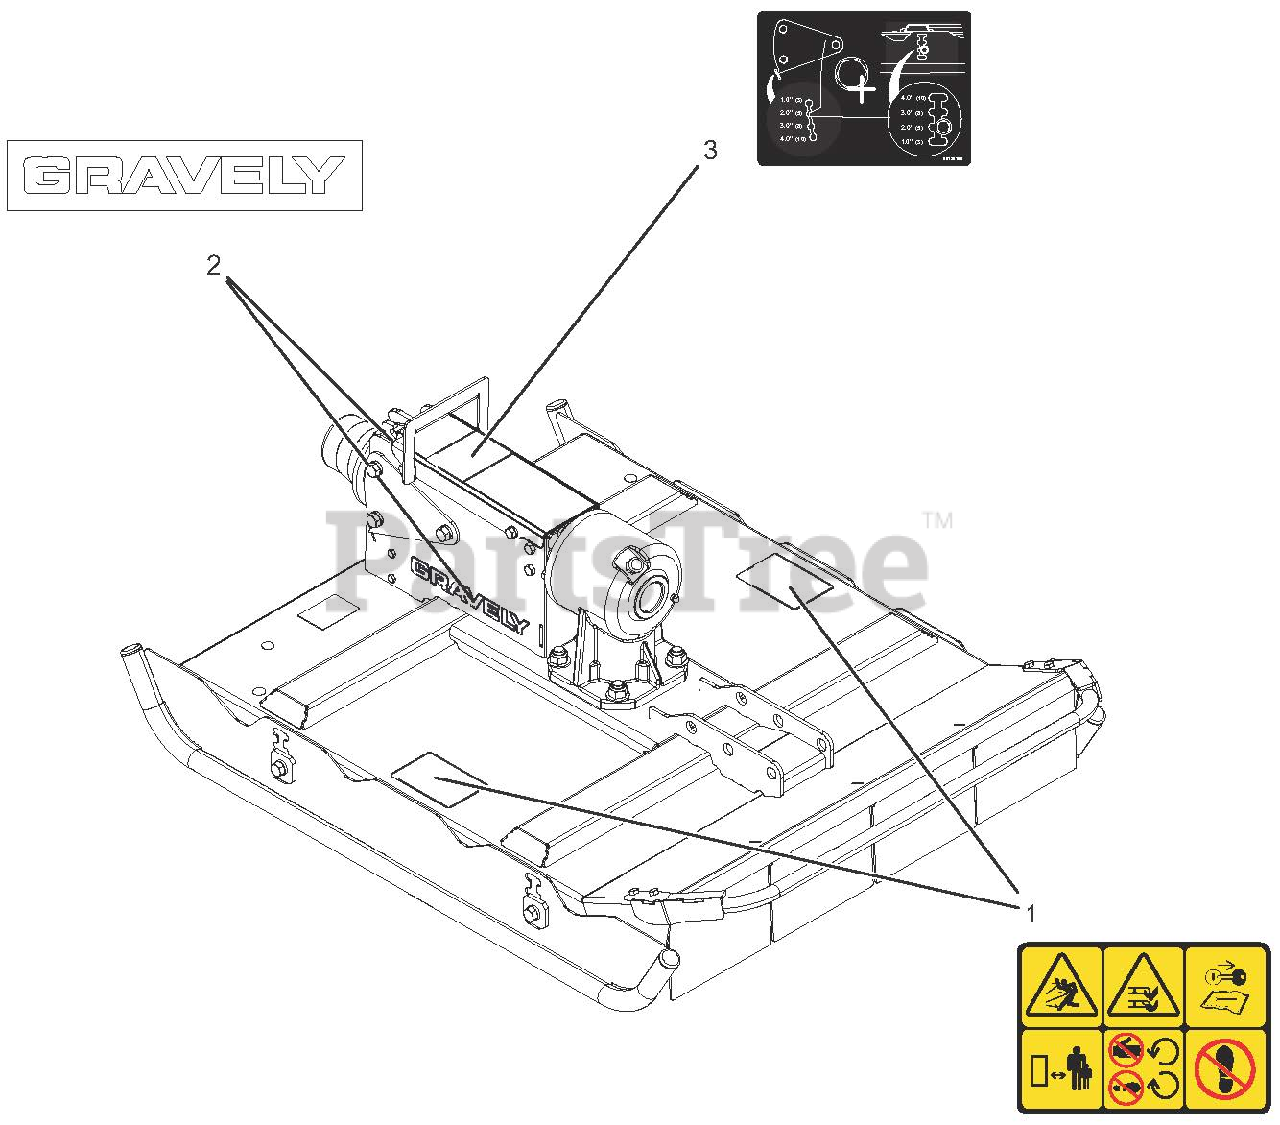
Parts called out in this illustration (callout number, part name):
1	DECAL, SAFETY - MOWER DECK
2	DECAL, 9.5" GRAVELY LOGO
3	DECAL, 32" BRUSH HOC ADJUST
